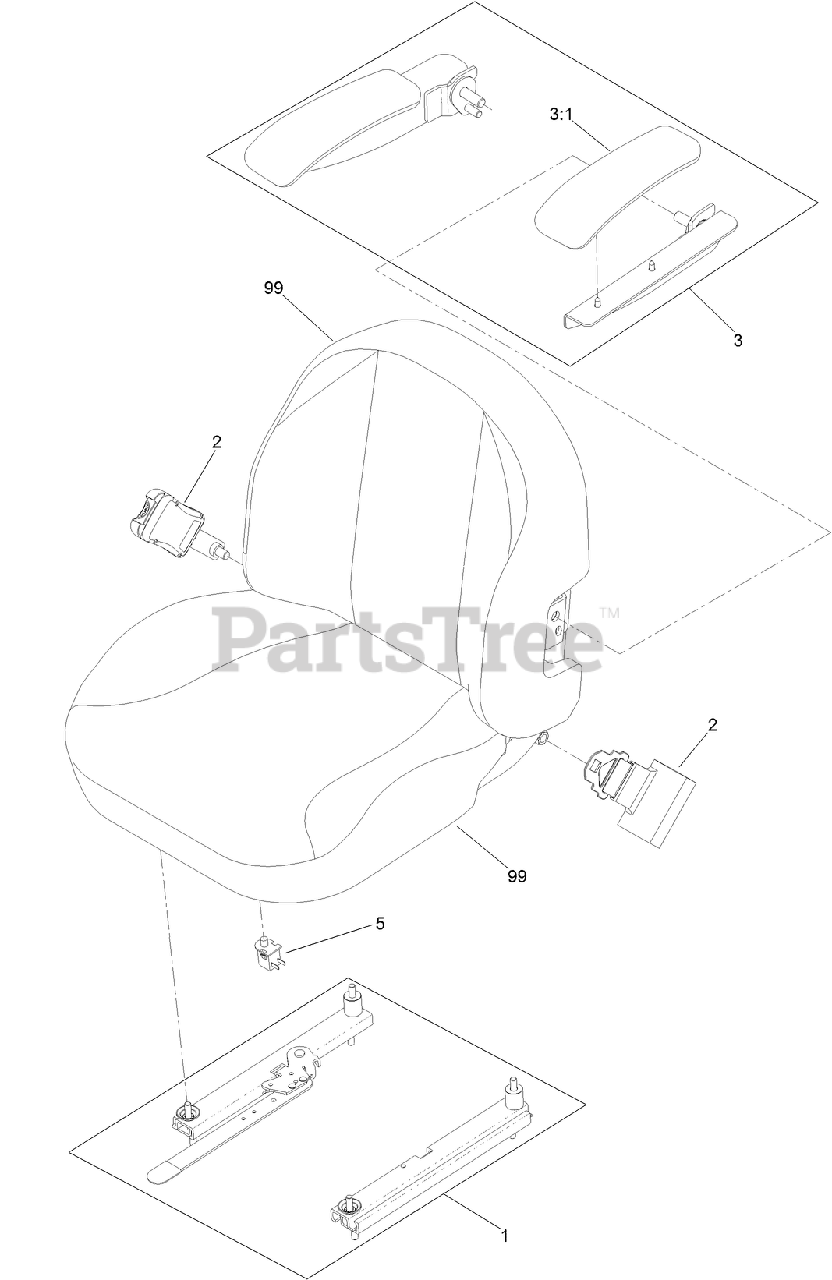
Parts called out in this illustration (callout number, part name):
1	SEAT TRACK KIT
2	SEAT BELT KIT
3	ARMREST KIT
3:1	CUSHION-REST, ARM
5	SWITCH-BAIL
99	COVER-SEAT, BOTTOM
99	COVER-SEAT, BACK
